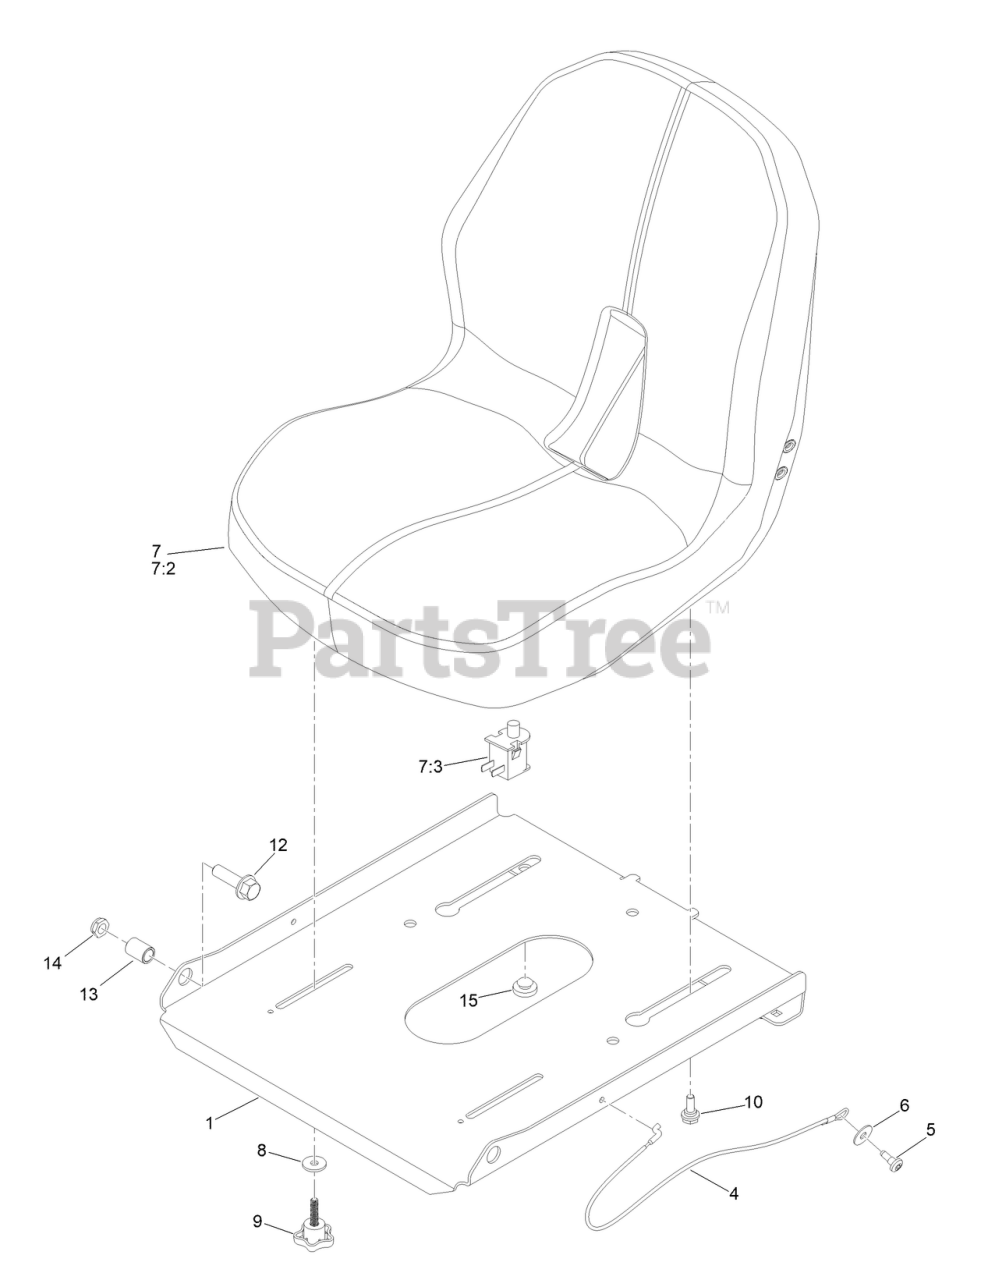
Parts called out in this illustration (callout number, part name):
1	PAN-SEAT, LOWERED
4	CABLE-LANYARD
5	SCREW-SHOULDER
6	WASHER-FLAT
7	SEAT-SHIELD HD
7:2	SWITCH-BAIL
7:3	COVER-SEAT
8	WASHER-FRICTION
10	BOLT-SHOULDER,HFH
12	SCREW-HHF
13	BUSHING-PIVOT, SEAT
14	NUT-HEX
15	BUMPER-SEAT
